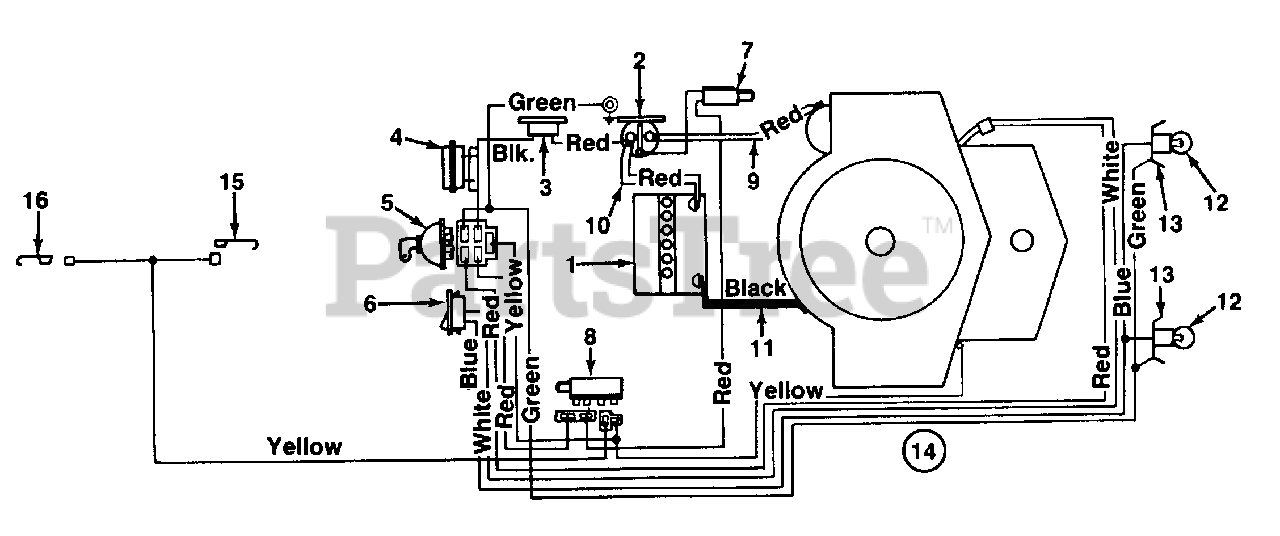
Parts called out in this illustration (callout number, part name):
1	Battery
2	Solenoid
3	Circuit Breaker
4	Ammeter
5	Ignition Switch
6	Light Switch
7	Safety Switch
8	Safety Switch
9	Electric Wire 14" Lg.
10	Electric Wire 7.5" Lg.
11	Ground Wire 7.5" Lg.
12	Lamp
13	Socket
14	Wire Harness
15	Spring Switch
16	Spring Switch
